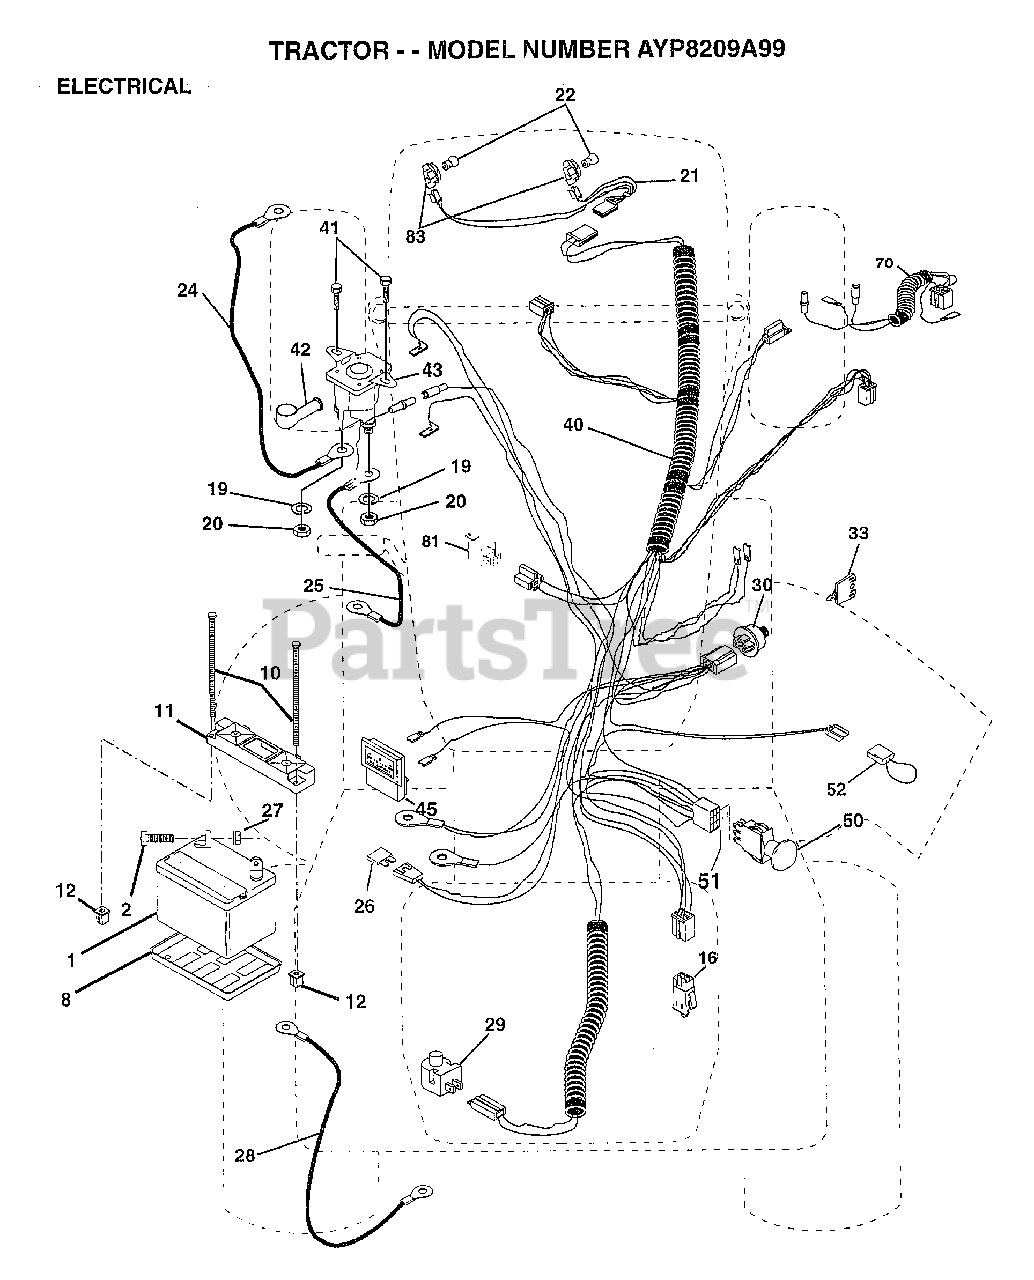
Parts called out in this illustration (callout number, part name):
2	BOLT LT
8	"TRAY T, BATTERY"
11	HOLDDOWN BATTERY
20	NUT
21	HARNESS.ASM.LIGHT W/4152J
22	HEADLAMP BULB
24	CABLE-BATTERY T
25	CABLE.6GA.12.5.
26	FUSE HYT
27	NUT
28	CABLE T
29	SWITCH.PLUNGER
30	SWITCH.IGN.
33	KEY MLD GEN DELTA
40	HARNESS.IGNITION
41	SCREW
45	AMMETER
50	PTO SWITCH.BLK
51	RING RETAIN PTO
70	HARNESS.ENGINE
81	RELAY ASSY T
